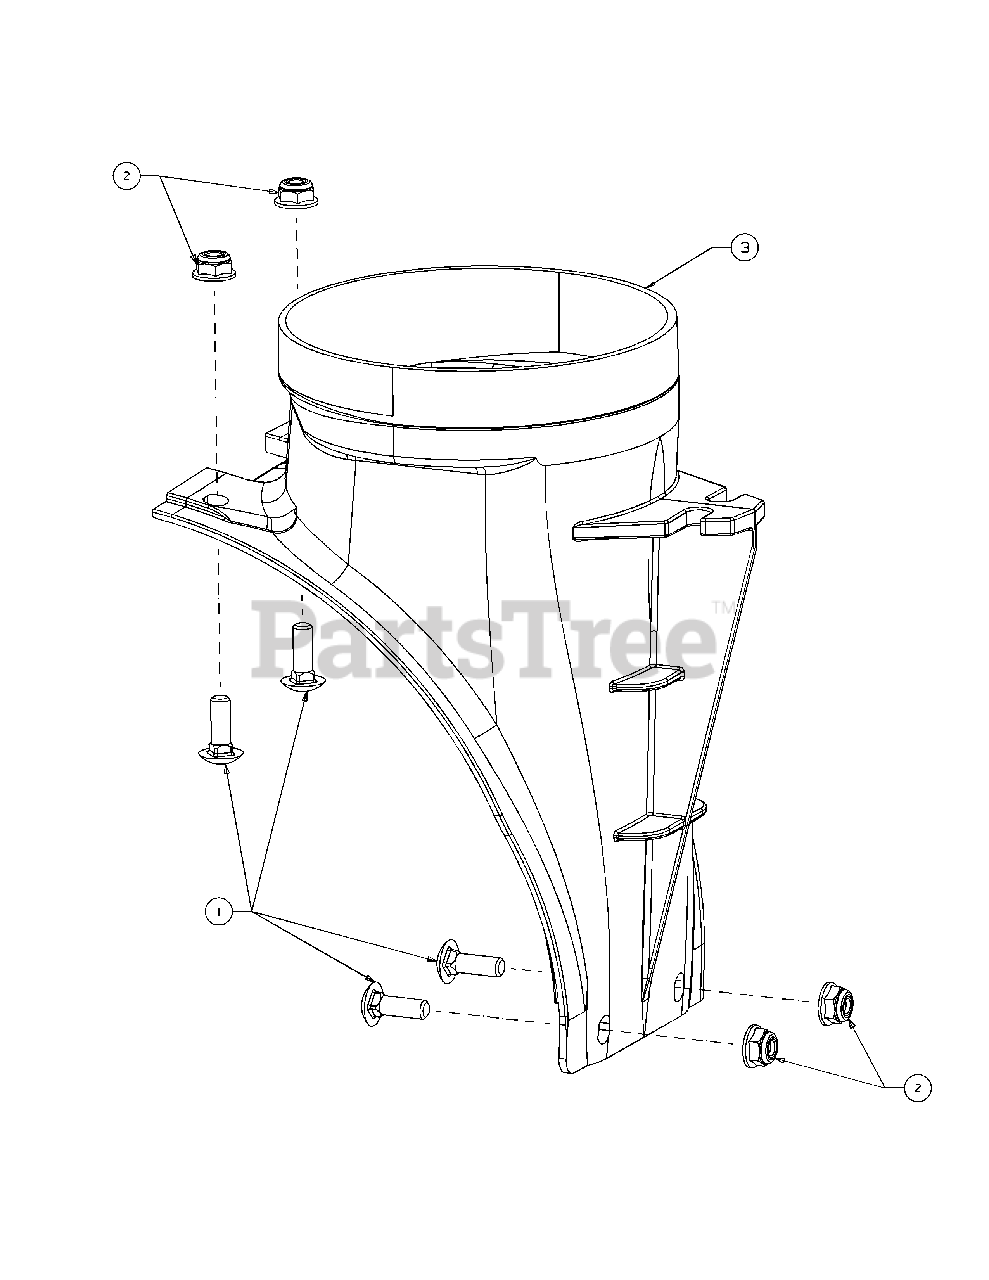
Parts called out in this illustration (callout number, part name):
1	Carriage Bolt 1/4-20 X .75
2	Nut-Flglk
3	Adapter-Chute 5"
